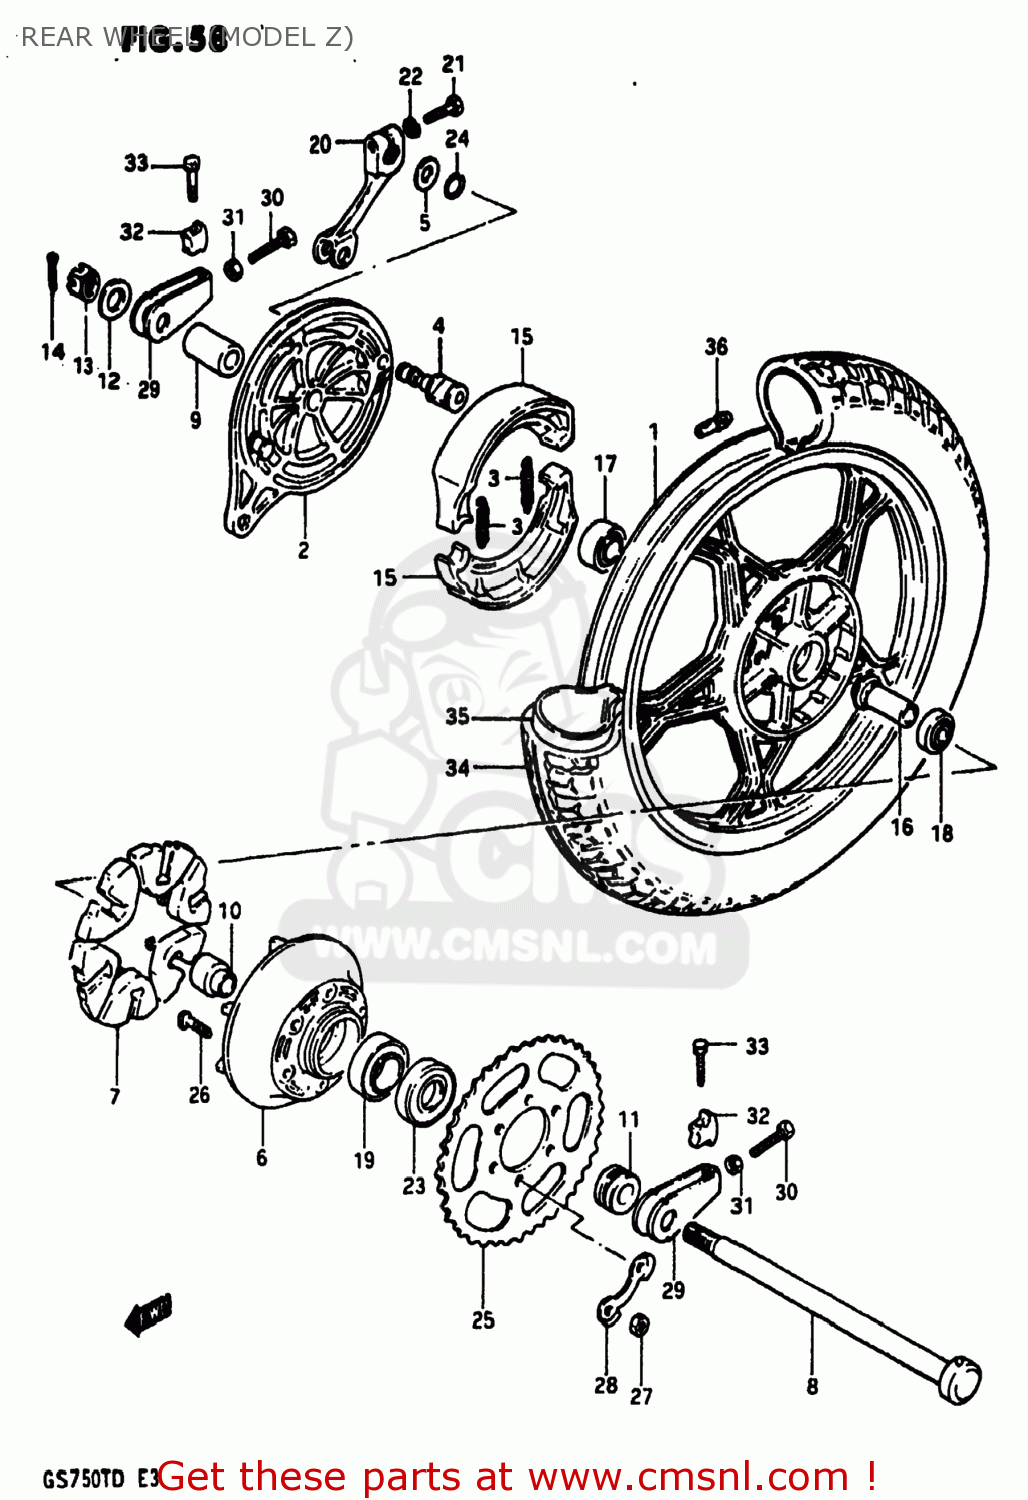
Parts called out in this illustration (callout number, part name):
1	WHEEL,REAR
3	SPRING,BRAKE SHOE
4	CAM,FRONT BRAKE
5	WASHER (16.5X42X2.6)
6	DRUM,REAR SPROCKET MOUNT
7	ABSORBER,REAR HUB SHOCK
8	AXLE,REAR
9	SPACER
10	SPACER,REAR HUB BEARING
11	SPACER(20X33X28.3)
12	WASHER(19X34X4)
13	NUT 18MM
14	PIN,COTTER
15	SHOE,BRAKE (MCA)
16	SPACER,REAR HUB BEARING
17	BEARING
18	BEARING, LH
19	BEARING
20	LEVER,REAR BRAKE CAM
21	BOLT
22	LOCK WASHER
23	SEAL,OIL(33X62X7)
24	O RING(D:2.4,ID:15.8)
25	SPROCKET,RR
26	BOLT
27	NUT
28	WASHER
29	ADJUSTER,CHAIN
30	BOLT 8X50
31	NUT
32	SUPPORTER,CHAIN ADJUST
33	BOLT (8X40)
34	TIRE
35	TUBE ASSEMBLY,WHEEL,INNER
36	BALANCER,WHEEL
